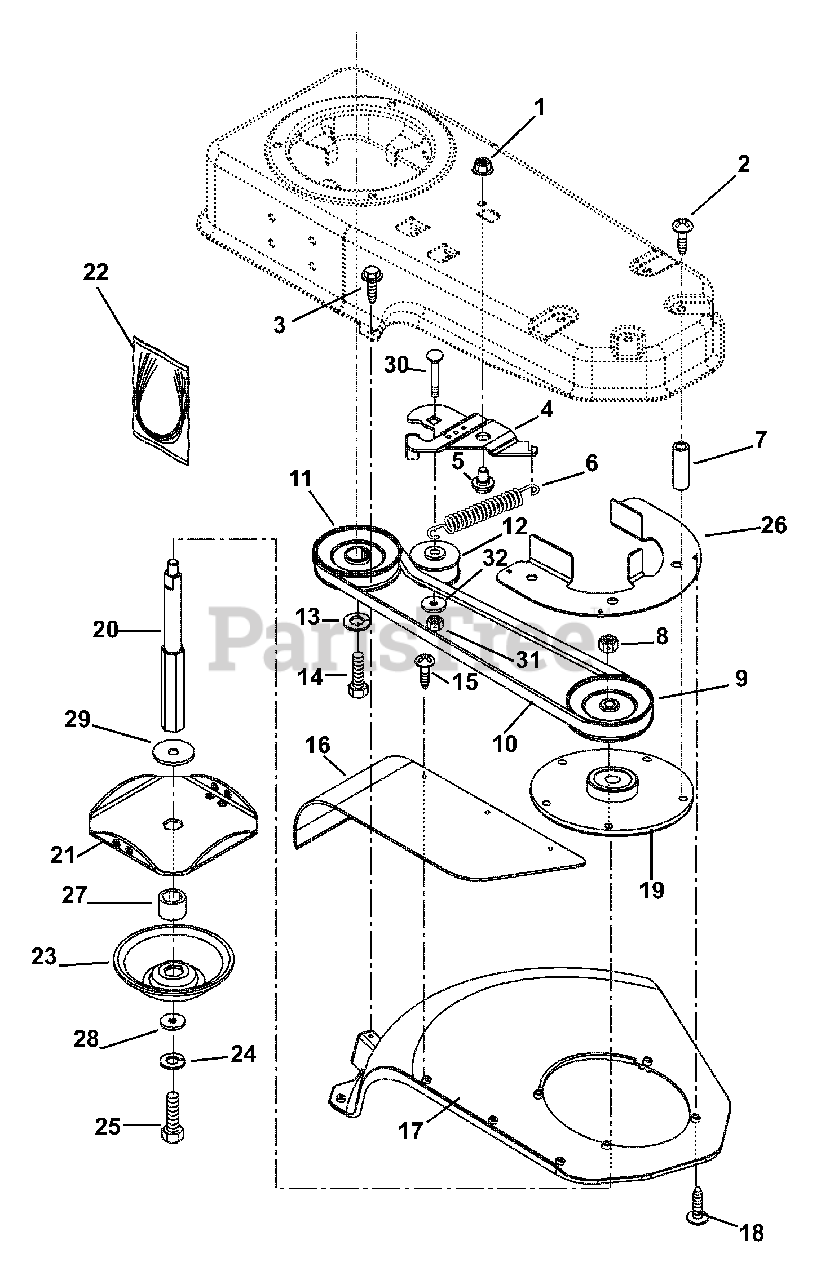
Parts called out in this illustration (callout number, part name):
1	Nut-Locking- Flange .38-16
2	Screw-Tapping .38-16 x 2.75
3	Screw-Tapping 10-24 x .75
4	Bracket-Idler
5	Bolt-Shoulder .38-16 x .135
6	Spring-Tension .035 x .45 x 2.75
7	Spacer-Jackshaft
8	Nut-Locking-Flange .38-24 Grade 5
9	Pulley-V 3.50 O.D. x .87 Wide (Cut)
10	Belt-V A-RMA 46.06 x .50
11	Sheave-Engine 3.50 O.D. x .87 Wide
12	Idler-Flat 1.88 O.D. x .75 Wide
13	Washer-Locking .38 x .94 Regular
14	Bolt-Hex .38-24 x 1.00
15	Screw-Tapping 10-16 x .625 Hex Washer Head
16	Guard-Debris
17	Shield-Trimmer
18	Screw-Tapping 10-24 x .75
19	Housing-Jackshaft
20	Shaft-Cutter-Hex
21	Disc-Cutter-Hex
22	Line-Cutter 18" (Pack of 6)
23	Guide-Height-Hex
23	Guide-Height-Long Life
24	Washer-Locking .31 x .078
25	Bolt-Hex .31-18 x .75 Grade 5
26	Finger-Belt
27	Spacer-Hex
28	Washer-Flat-Steel .344 x 1.13 x .135
29	Shield-Dust
30	Bolt-Round Head Short Square Neck .38-16 x 1.50 Grade 5
31	Nut-Locking-Center .38-16
32	Washer-Flat-Steel .406 x .812 x .065
